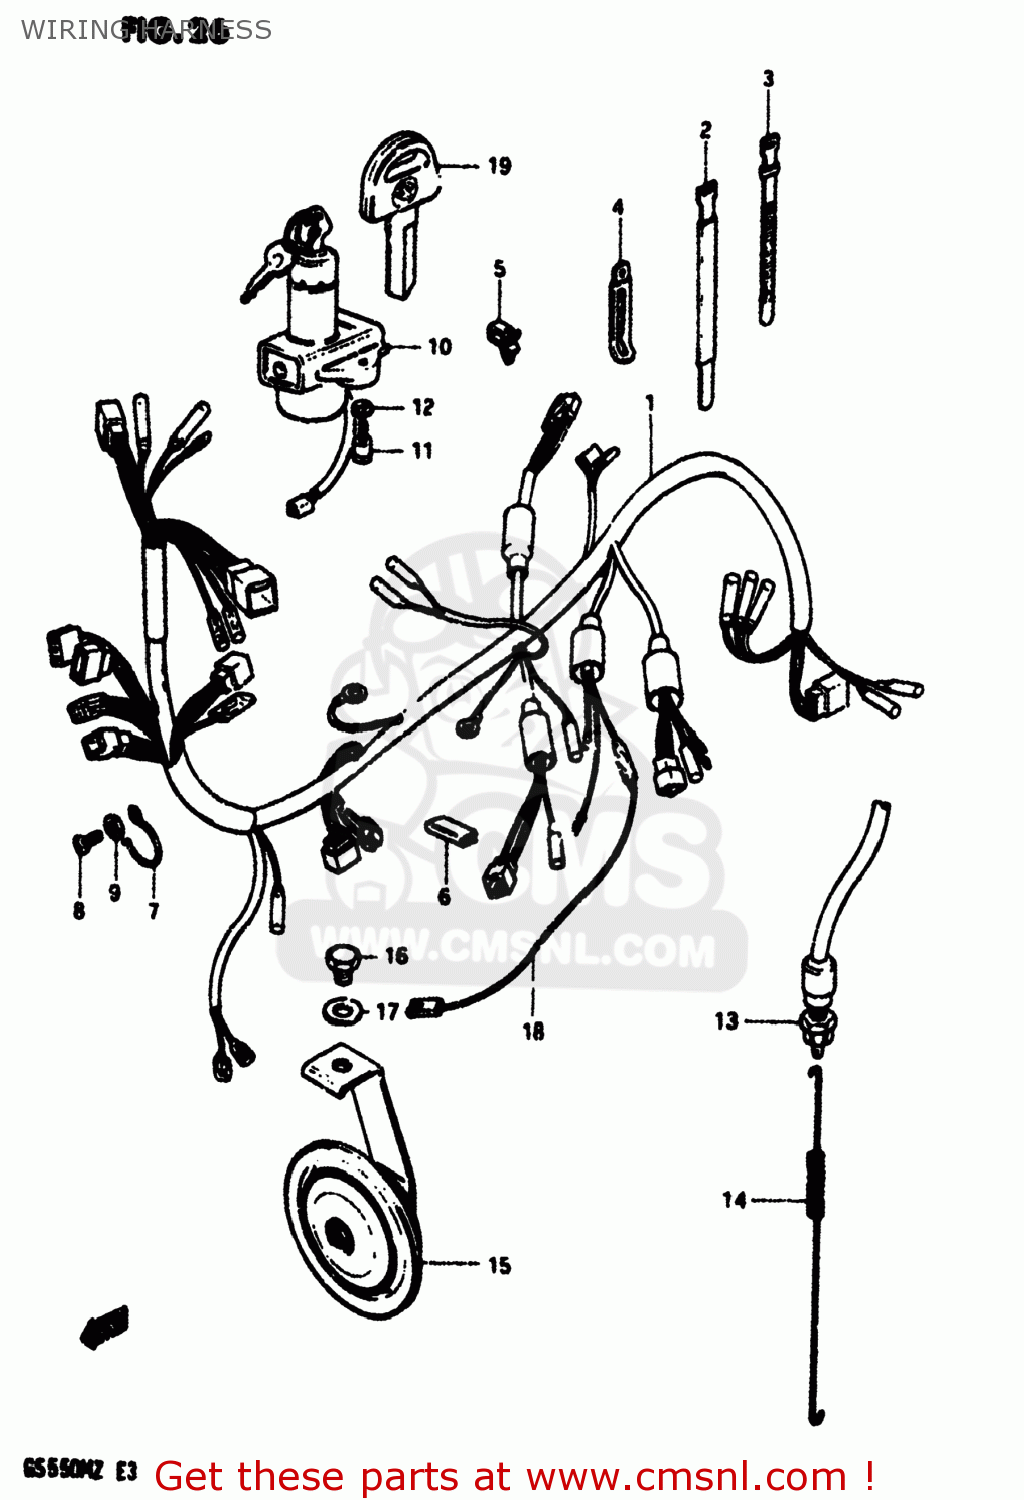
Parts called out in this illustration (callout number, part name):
1	HARNESS,WIRING
2	CLAMP
3	CLAMP(L:120)
4	CLAMP
5	CLIP
6	PROTECTOR,WIRING HARNESS
7	GUIDE,WIRING HARNESS
8	SCREW 6X12
9	WASHER
10	LOCK ASSEMBLY,STEERING
11	BOLT
12	LOCK WASHER
13	SWITCH ASSEMBLY,BRAKE LAMP
14	SPRING
15	HORN ASSEMBLY
16	BOLT 8X12
17	WASHER
18	WIRE
19	KEY,BLANK
